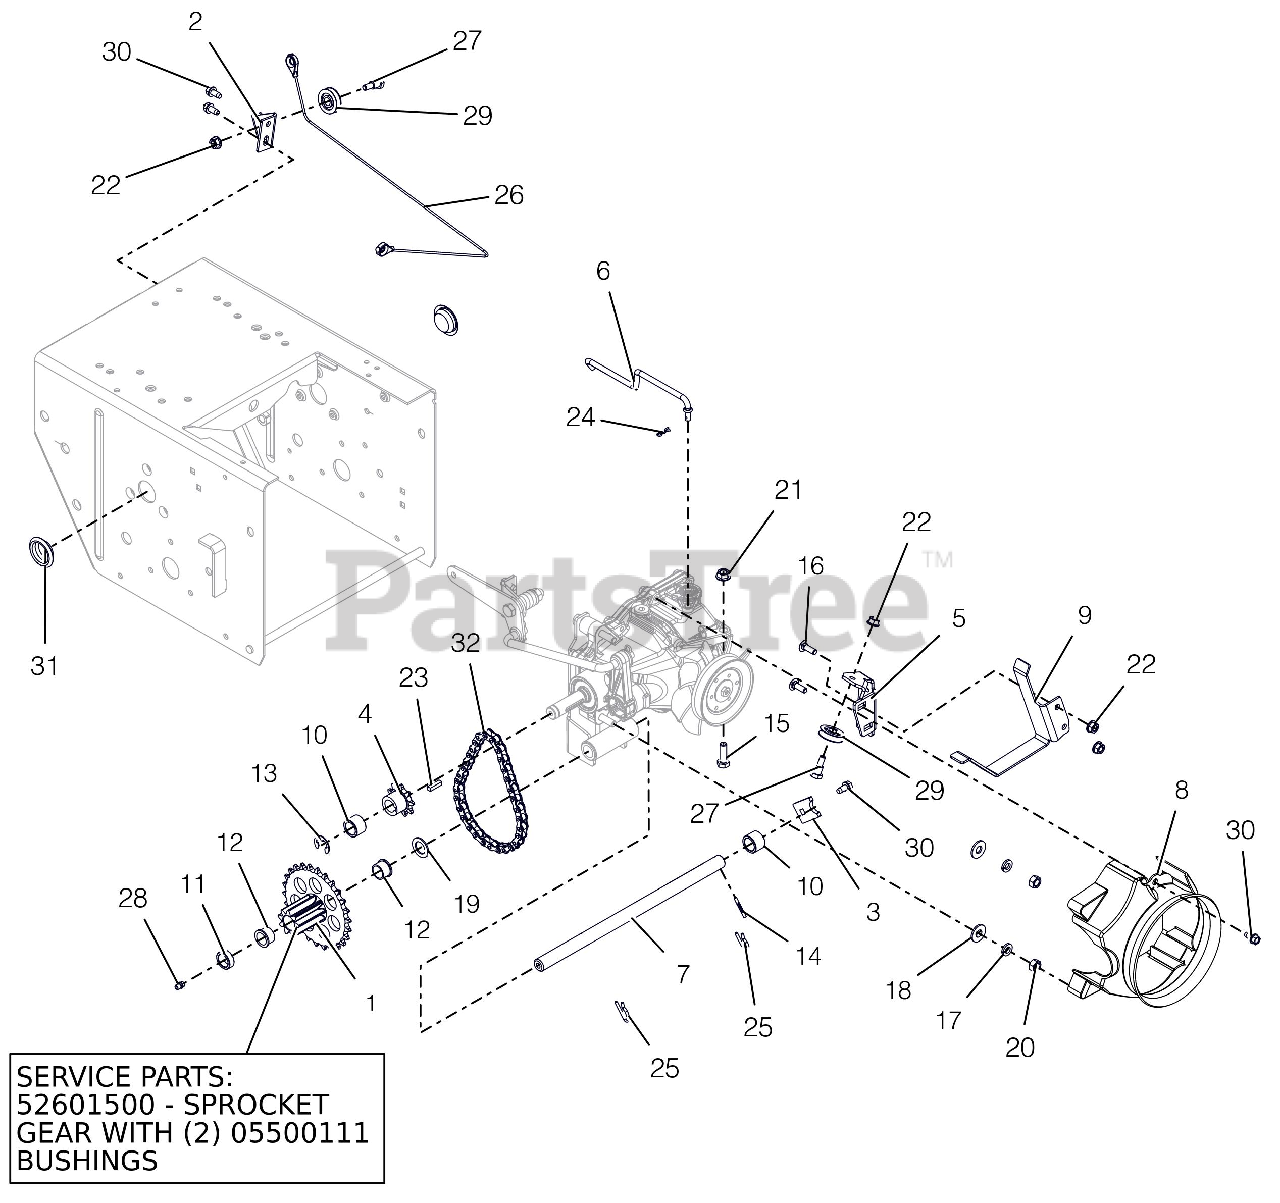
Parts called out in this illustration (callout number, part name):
1	PINION & SPROCKET
1	PINION & SPROCKET W/BUSHINGS
1	BSHG-FLG .625X.750X.500X.875
2	BRACKET, CABLE PULLEY
3	TAB, ANTI ROTATION
4	SPROCKET, PINION 9T W/KEY
5	BRACKET, CLUTCH CABLE
6	ROD, HYDRO BYPASS
7	SHAFT, PINION - HARDENED
8	SHROUD, HYDROGEAR RT-310
9	FINGER, BELT - FLAT
10	SPACER, .635X.880X.611
11	BSHG-SLV, .635X.880X.305
12	BSHG-FLG .625X.750X.500X.875
13	RG-RTNG-EXT .625X.042
14	@PIN-GRV .125X1.00 TP E ALLOY
15	@BLT-HEX .31-18X1.00 GR5 YWZC
16	@BLT-RDHDSQNK .25-20X.75 G5YZ
17	WSHR-LK .312X.097 HVY YWZC
18	@WSHR-FL-STL.38X.875X.083 YWZC
19	WSHR-FL-STL .630X1.005X.062 YZ
20	@NUT-HEX .31-18 YWZC
21	@NUT-LK-TOP-FLG .31-18 YWZC
22	@NUT-LK-TOP-FLG .25-20 YWZC
23	KEY-SQ .188X.75X.188
24	PIN-HAIR INT .06X.18X.77
25	PIN, SPRING CLIP
26	CABLE, TRACTION, HYDRO PRO
27	BOLT, SHLDR-.375X.375X.25-20
28	ZERK,FITTING .25X.125 DRIVE IN
29	PULLEY, CABLE
30	SCR-TAP .25-20X.50 HWH TR YWZ
31	PLUG, HOLE - 1.125"
32	CHAIN - #41, 32 PITCHES
